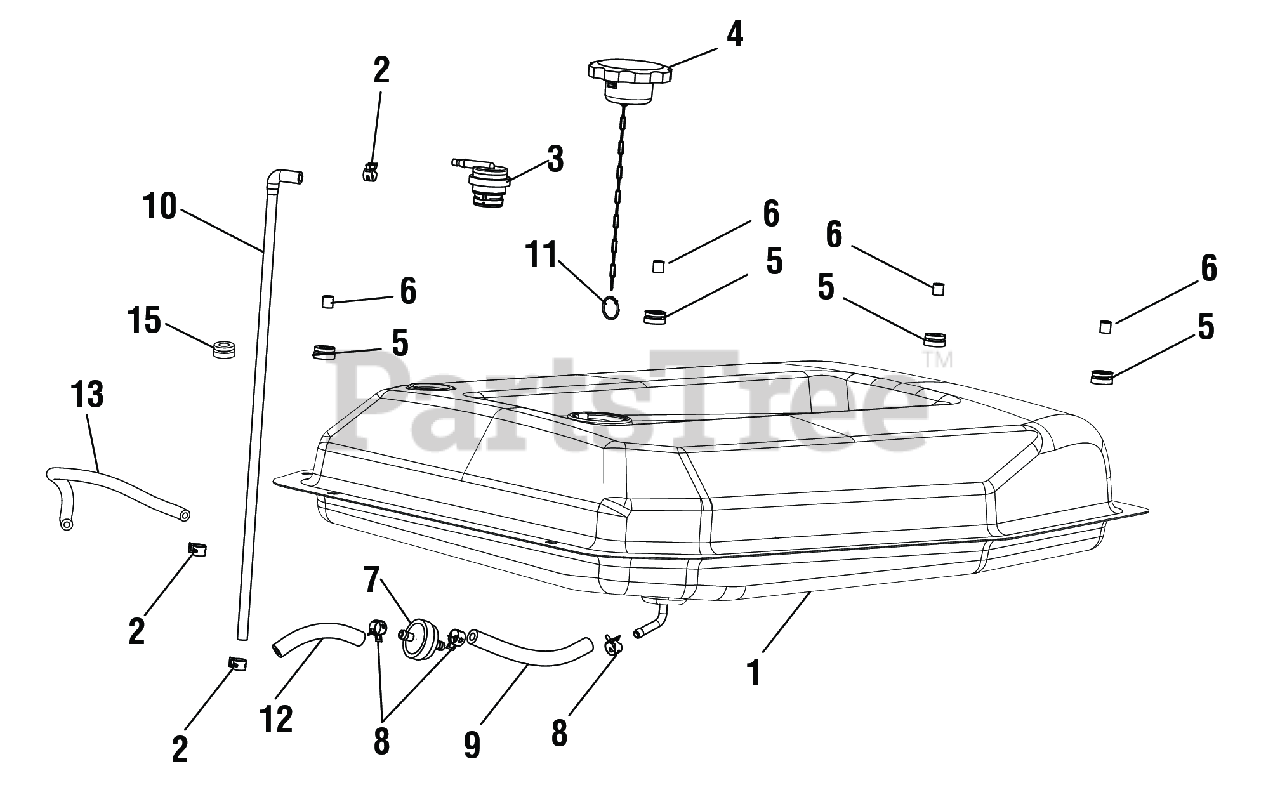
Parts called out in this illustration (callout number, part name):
1	Fuel Tank Assembly (See Fig. B)
2	Fuel Line Clamp (7/16 in., BM903611)
3	Fuel Tank Vapor Vent
4	Fuel Cap Assembly
5	Bushing (Fuel Tank Isolator)
6	Spacer (Fuel Tank Isolator)
7	Fuel Filter Inline (1/4 in.)
8	Fuel Line Clamp (1/2 in.).
9	Fuel Hose (175 mm)
10	Vapor Hose
11	Ring Clip
12	Fuel Hose (85 mm)
13	Fuel Hose (330 mm)
14	Fuel Hose Protector
